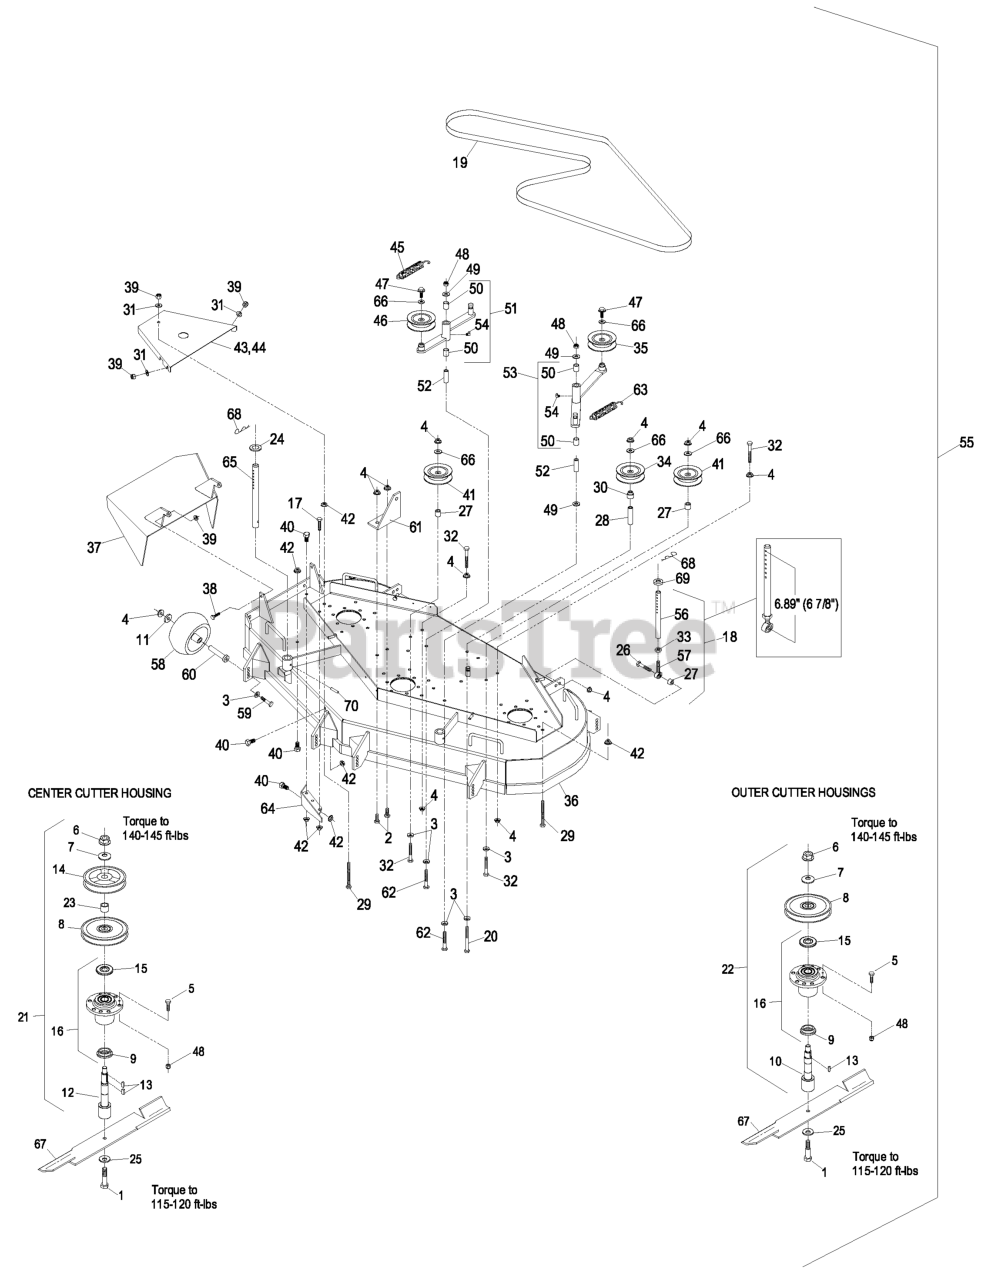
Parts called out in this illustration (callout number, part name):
1	SCREW-CAP
2	SCREW-HH
3	WASHER-BELLEVILLE
4	NUT-HHF, WHIZ
5	SCREW-HH
8	SHEAVE,BLADE DRIVE 6.30
9	SPACER-GUARD, BOTTOM
10	SPINDLE,SHORT
12	SPINDLE,LONG
14	SHEAVE,BLADE DRIVE
15	GUARD-BEARING, TOP
17	SCREW-HH
19	BELT,MULE DRIVE
20	SCREW-HH
23	SPACER,TUBE
24	SPACER-DECK SUPPORT
25	WASHER-BLADE BOLT, HEAVY
26	SCREW-HH
28	SPACER-ANCHOR, CLUTCH
29	BOLT,TAP HH
30	BUSHING,IDLER
31	WASHER-FLAT
32	BOLT-CARR
33	NUT-HEX
34	PULLEY-IDLER
35	PULLEY-IDLER
37	WLD,CHUTE FMD604
38	SCREW-HH
39	NUT-LOCK, NI
40	SCREW-HH
41	IDLER,PULLEY
43	SHIELD,BELT RH
44	SHIELD,BELT LH
45	SPRING-EXTENSION
46	IDLER,PULLEY
47	SCREW-HHF
48	NUT-LOCK, NI
49	WASHER-FLAT
50	SLEEVE-BEARING
51	ASM,IDLER ARM
52	BUSHING-PIVOT, IDLER
53	ASM,IDLER ARM
54	FITTING-GREASE, 90 DEG
55	Complete Deck Assy
56	LINK,SUPPORT
57	BALLJOINT
58	ROLLER-SCALP, ANTI
59	SCREW-HH
60	BUSHING-ROLLER
61	BRACKET,SPRING ANCHOR
62	SCREW-HH
63	SPRING-EXTENSION
64	WLD,BAFFLE DISCHARGE
65	ROD,DECK SUPPORT
66	WASHER-FLAT
68	PIN,HAIR COTTER
